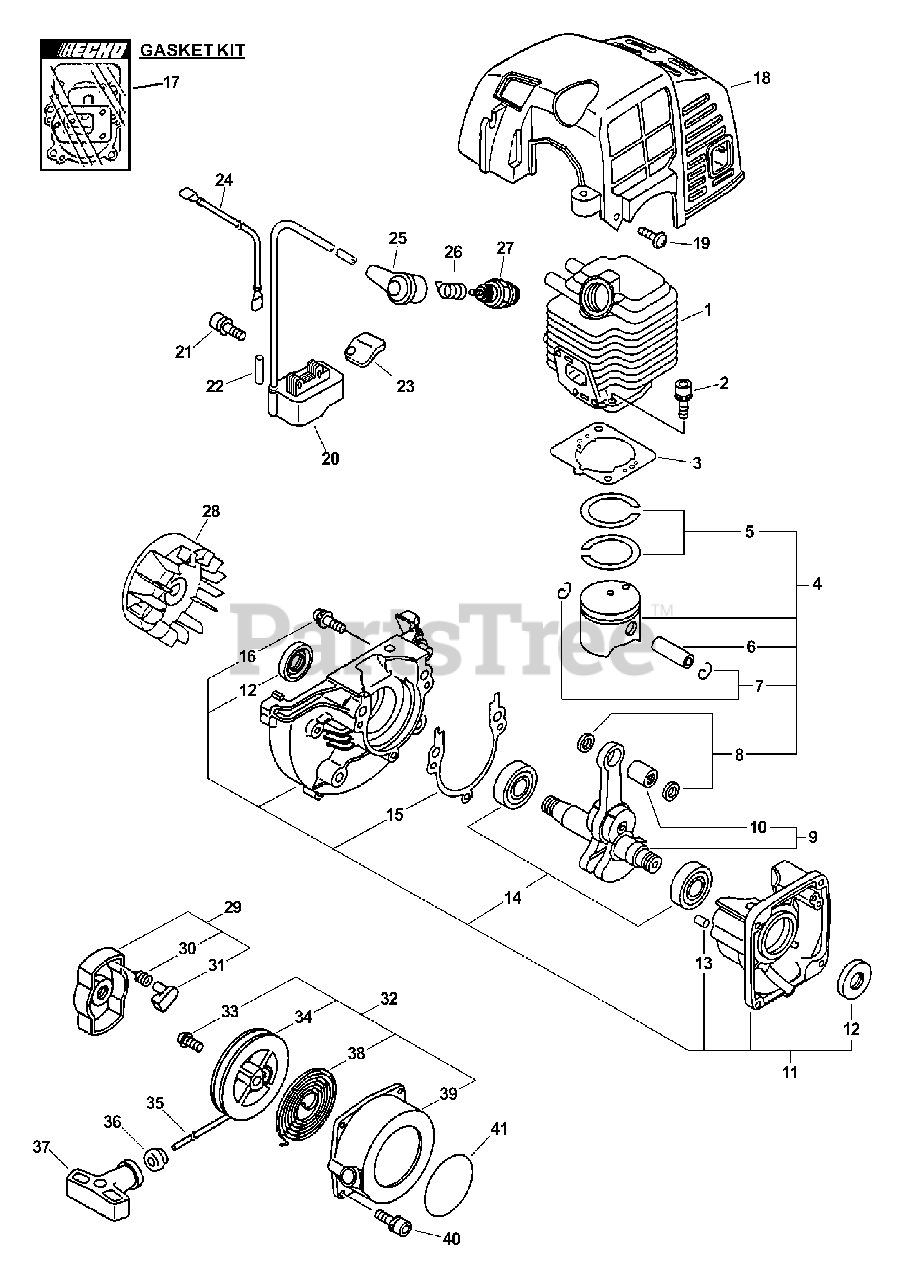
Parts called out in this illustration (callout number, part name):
1	CYLINDER
2	BOLT 5×22
3	GASKET, CYLINDER
4	PISTON KIT
5	RING, PISTON
6	PIN, PISTON 8
7	RING, SNAP
8	WASHER, THRUST
9	CRANKSHAFT ASSY
10	BEARING, NEEDLE 8
11	CRANKCASE KIT
12	SEAL, OIL 12
13	PIN, LOCATING 4
14	BEARING, BALL - 6201 C3
15	GASKET, CRANKCASE
16	BOLT 5×28
17	GASKET KIT
18	COVER, CYLINDER
19	SCREW 4×14
20	COIL, IGNITION
21	BOLT 4×20
22	TUBE, INSULATOR
24	LEAD
25	CAP, SPARK PLUG
26	TERMINAL, SPARK PLUG
27	SPARK PLUG - BPM8Y
28	FLYWHEEL
29	PAWL ASSY, STARTER
30	SPRING, RETURN
31	PAWL, STARTER - BLACK
32	STARTER ASSY, RECOIL
33	SCREW
34	REEL, ROPE
35	ROPE, STARTER 3.0×1000
36	GUIDE, ROPE
37	GRIP, STARTER
38	SPRING, RECOIL
39	CASE, RECOIL STARTER
40	SCREW 4×16
41	LABEL, ECHO
